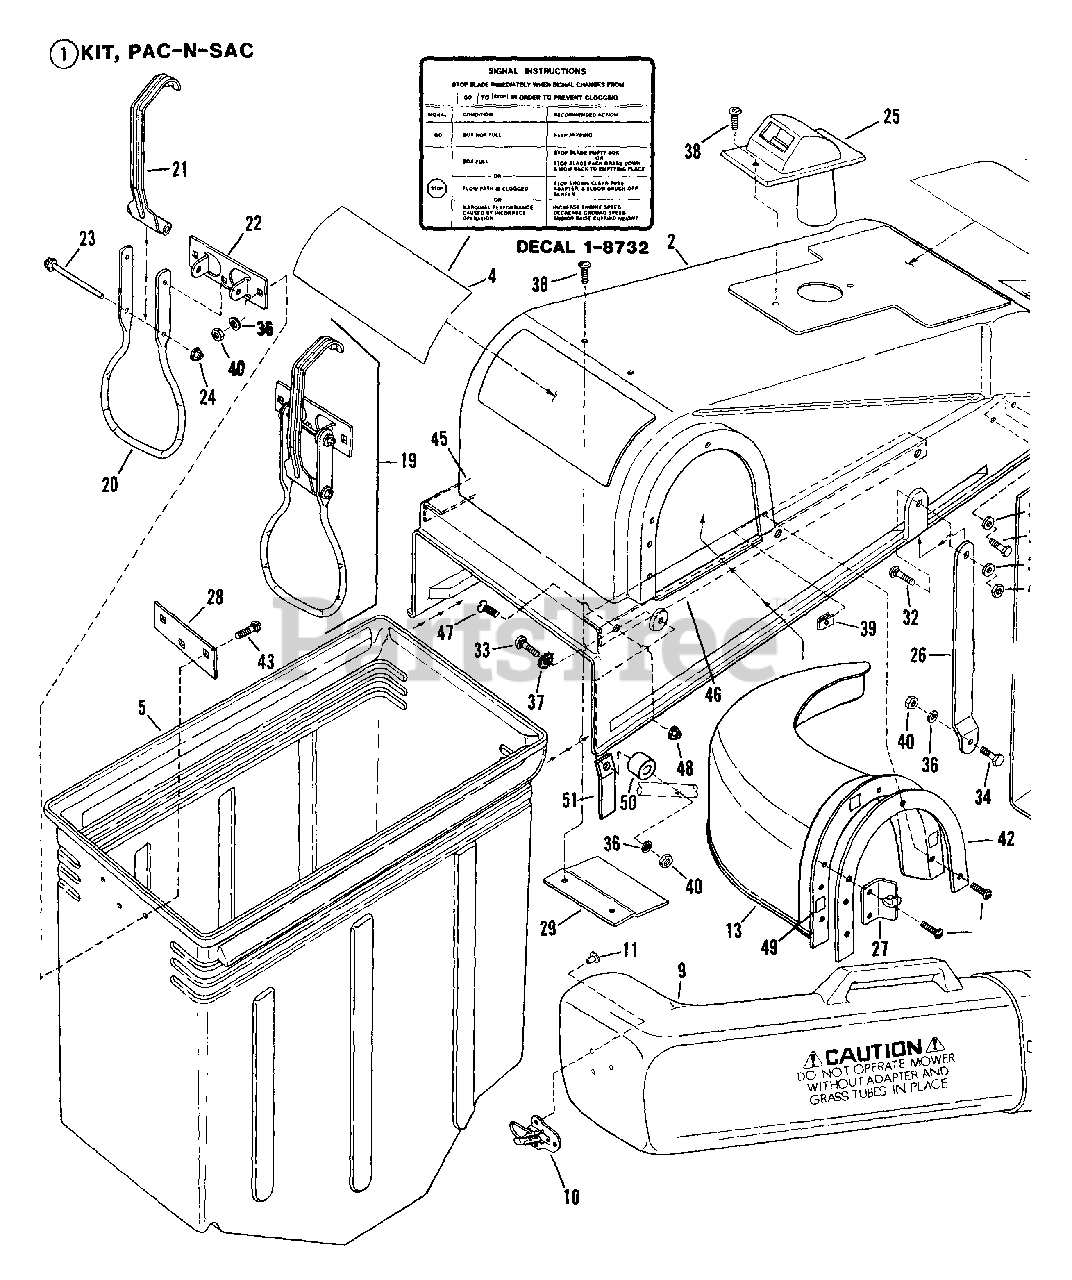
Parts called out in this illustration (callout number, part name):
1	KIT, Pac-N-SAC
2	ASSEMBLY, Cover
4	DECAL, Operation
5	CONTAINER
9	ASSMY, Grass Tube
10	DRAWBOLT, Bottom
11	EYELET, Flat Flange
13	DEFLECTOR
19	ASSEMBLY, Handle
20	HANDLE, Latch
21	LATCH, Container
22	PIVOT, Latch
23	PIN, Latch
24	NUT, 5/32" Self-Threading
25	ASSEMBLY, Indicator
26	BRACE (88' Models & Earlier)
27	DRAWBOLT, Top
28	PLATE, Pivot
29	RETAINER, Screen
32	CARRIAGE BOLT, 1/4-20 x 5/8" Short Neck
33	CARRIAGE BOLT, 1/4-20 x 1-3/4" Short Neck
34	CAPSCREW, 1/4-20 x 1 1/2 Hex Head
36	LOCKWASHER, 1/4" Internal Tooth
37	WASHER, Int./Ext. Tooth Lock
38	MACHINE SCREW, #10 - 16 x 3/4" Slotted
39	NUT, #10 - 16 Clip
40	NUT, 1/4-20 Hex
43	BOLT, 1/4-20 x 3/4" Short Neck
45	SEAL, Left Hand
46	SEAL, Right Hand
47	SCREW, #10-24 x 1/2" FH Machine
48	NUT, #10-24 Acorn
49	ADHESIVE SQUARE
51	SUPPORT, Side
